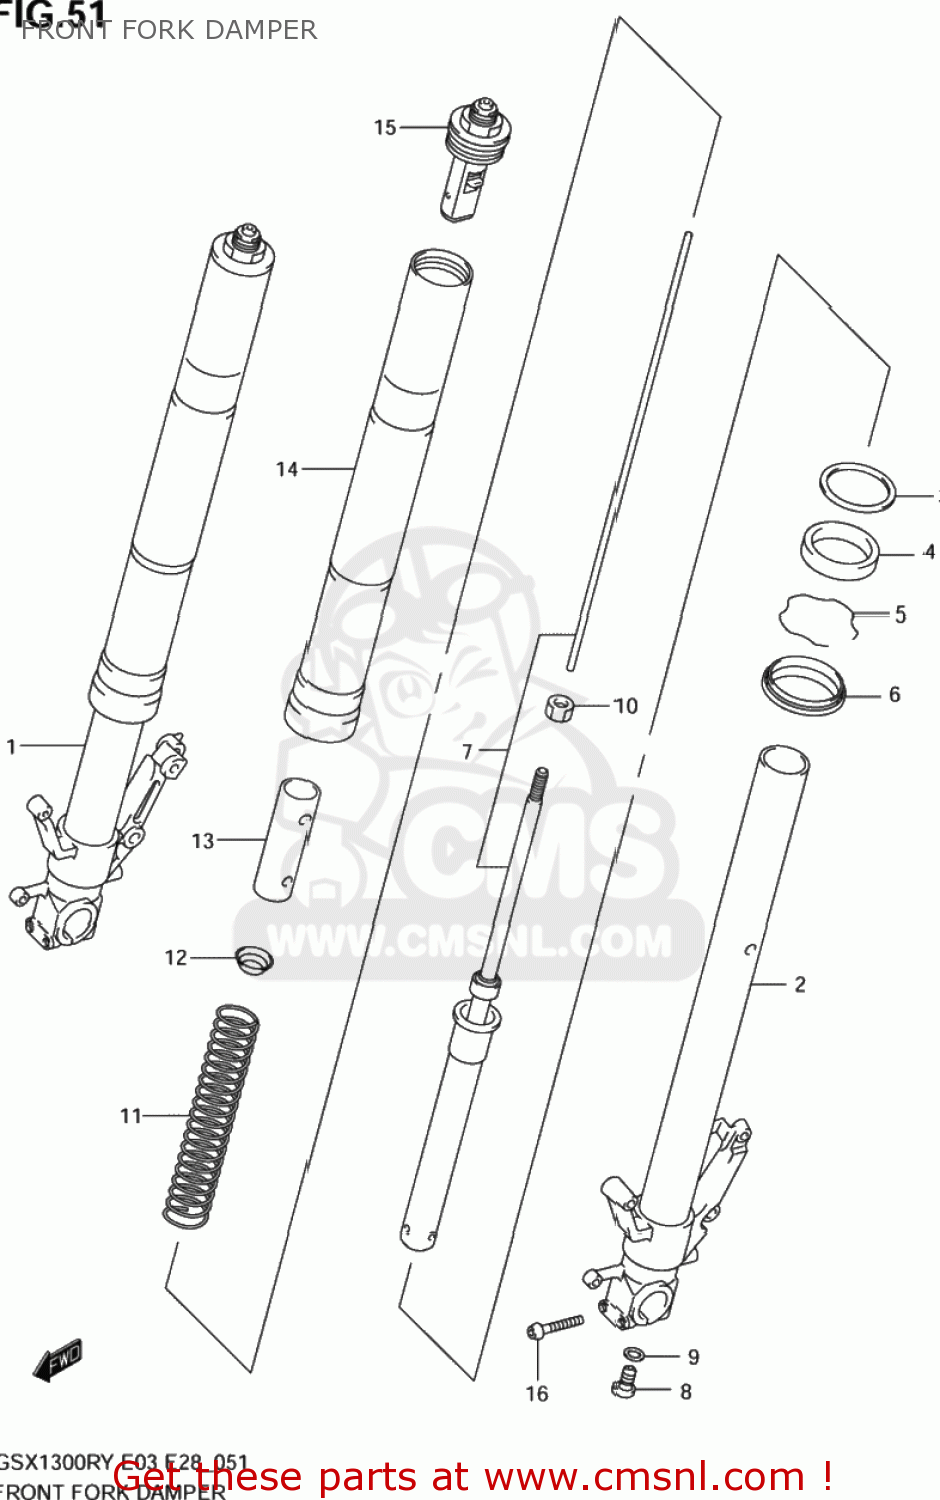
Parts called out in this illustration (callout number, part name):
1	TUBE,INNER,R(BLACK)
2	TUBE,INNER,L(BLACK)
3	WASHER
4	SEAL,OIL
5	RING,STOPPER
6	SEAL,DUST
7	CYLINDER
8	BOLT,OIL LOCK PIECE,12X22
9	GASKET,CYLINDER (NAS)
10	NUT
11	SPRING,FR
12	GUIDE,SPRING
13	SPACER,SPRING
14	TUBE
15	CAP,FR FORK
16	BOLT 8X45
